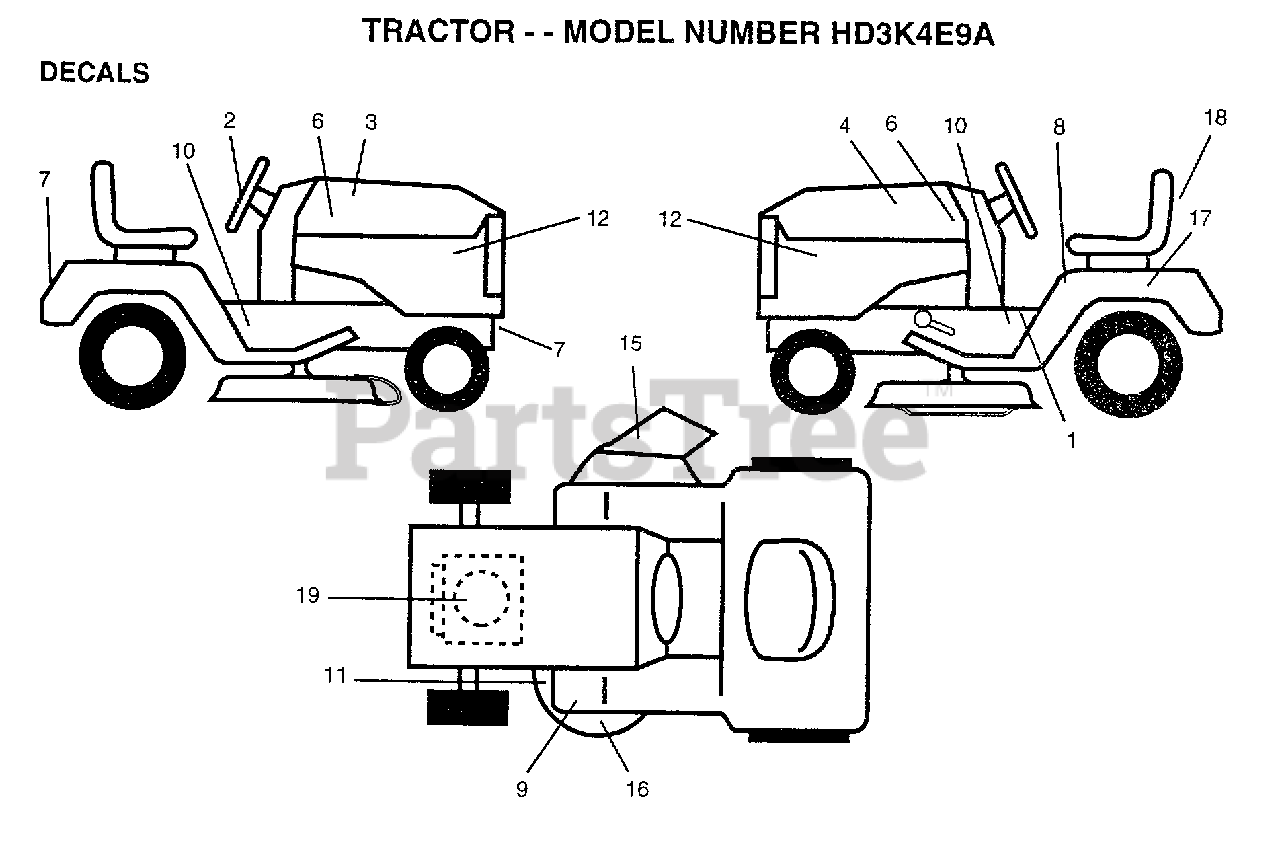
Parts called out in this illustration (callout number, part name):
1	DECAL.SADDLE.INST
2	DECAL.INST.WHL.ST
3	DECAL.HD.RH.14.5
4	DECAL.HD.LH.14.5
6	DECAL.FEND.QUICKS
7	DECAL.FENDER.HDEP
8	DECAL CAUT FEND
9	DECAL CLUT/BRAKE
10	DECAL.SCH.DRV.42
11	DECAL.SCH.PRIM.42
12	DECAL.PNL.SD.HDPO
15	"DECAL, WARNING"
16	DECAL.DECK.MULCH.
17	DECAL.BTRY.DANGER
18	DECAL.SEAT.ACC.
19	DECAL.PARTS.B&S.
